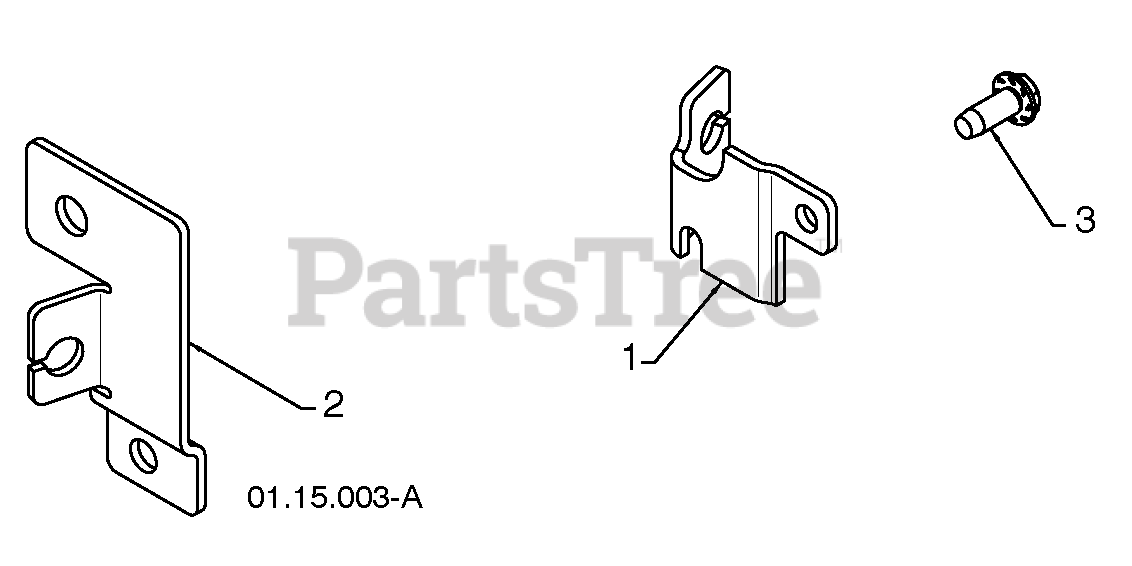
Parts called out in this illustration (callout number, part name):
1	CABLE BRACKET LH
2	CABLE BRACKET RH
3	SCREW 1/4-20 X .625
